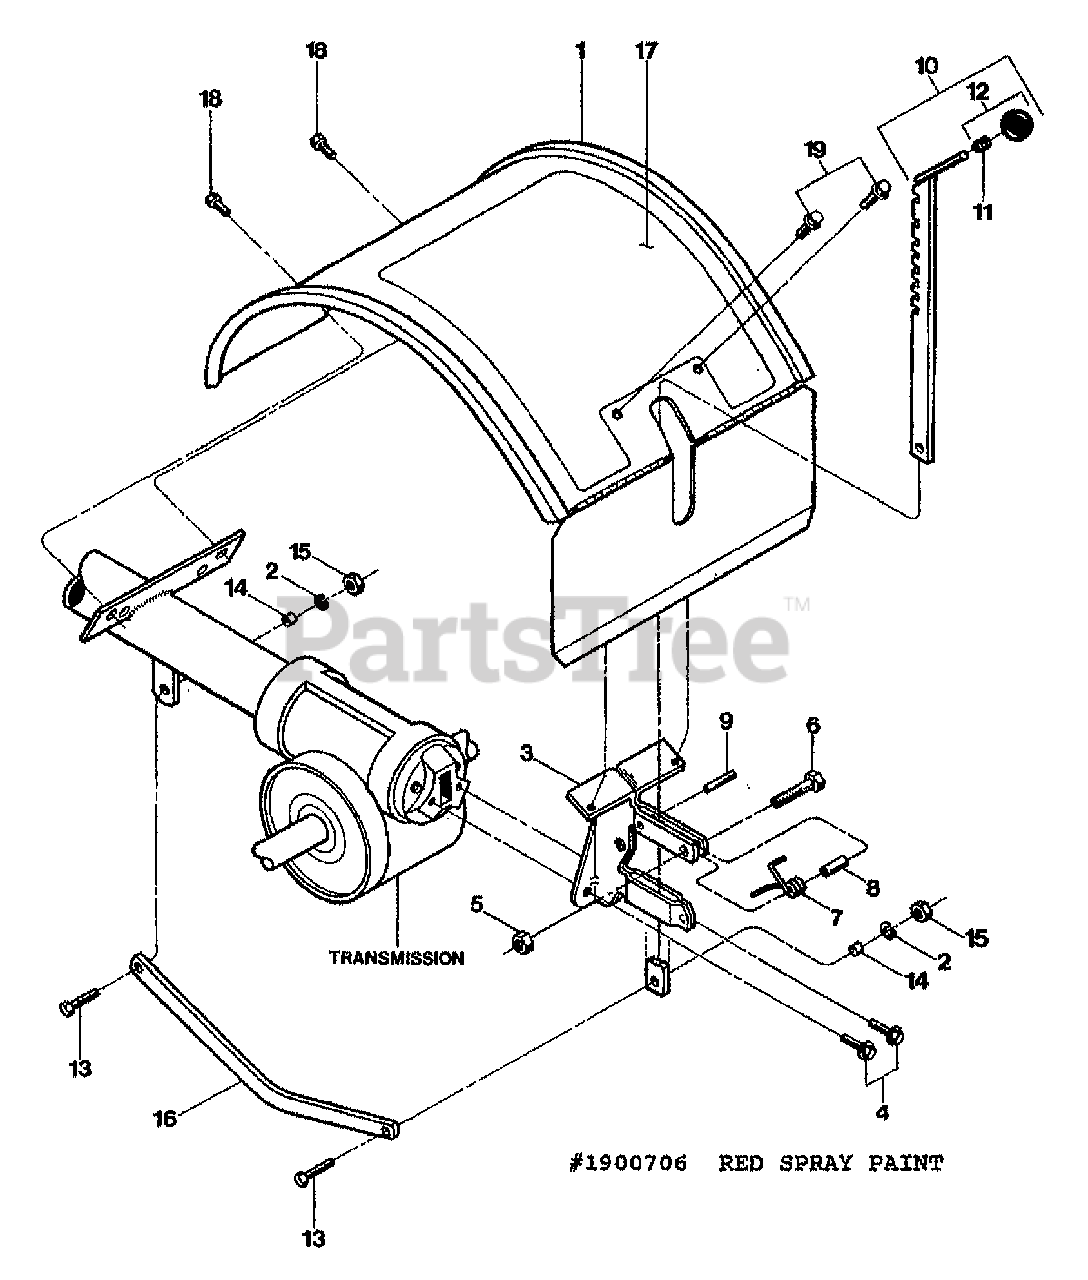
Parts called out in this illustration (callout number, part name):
1	HOOD W/DECALS PONY OPC (INCL. 17)
2	HOOD W/DECALS PONY (INCL 17) (15008,15009, 0400101 & HIGHER)
2	WASHER-LK .375 @ DEPL
3	BRKT W/ROLL PIN (9308)
4	SCR-HFLK 5/16-18X.62 G5ZP
5	NUT-LK 1/4-20
6	SCR-HH 1/4-20X1.0
7	SPRING-TORSION
8	SPACER-.250X.343X.375
9	PIN-ROLL .25 X 1
10	DEPTH REGULATOR W/KNOB (INCL. 11 & 12)
11	RING-TOLERANCE .5325 ID
12	KNOB-CONTROL (INCL. 11)
13	SCR-HH 3/8-16X1.25
14	BUSHING-.5X.375X.3
15	NUT-HEX 3/8-16 ZP
16	DRAG BAR-BENT
17	DECAL-HOOD OPER INST
17	DECAL-HOOD INST PONY (15008 & 15009 0400101 & HIGHER)
18	SCR-HWH 5/16-18 X .5 STH
19	SCR-HWH 1/4-20 X .5 STH (ATTACHES HOOD TO DEPTH REGULATOR BRACKET)
